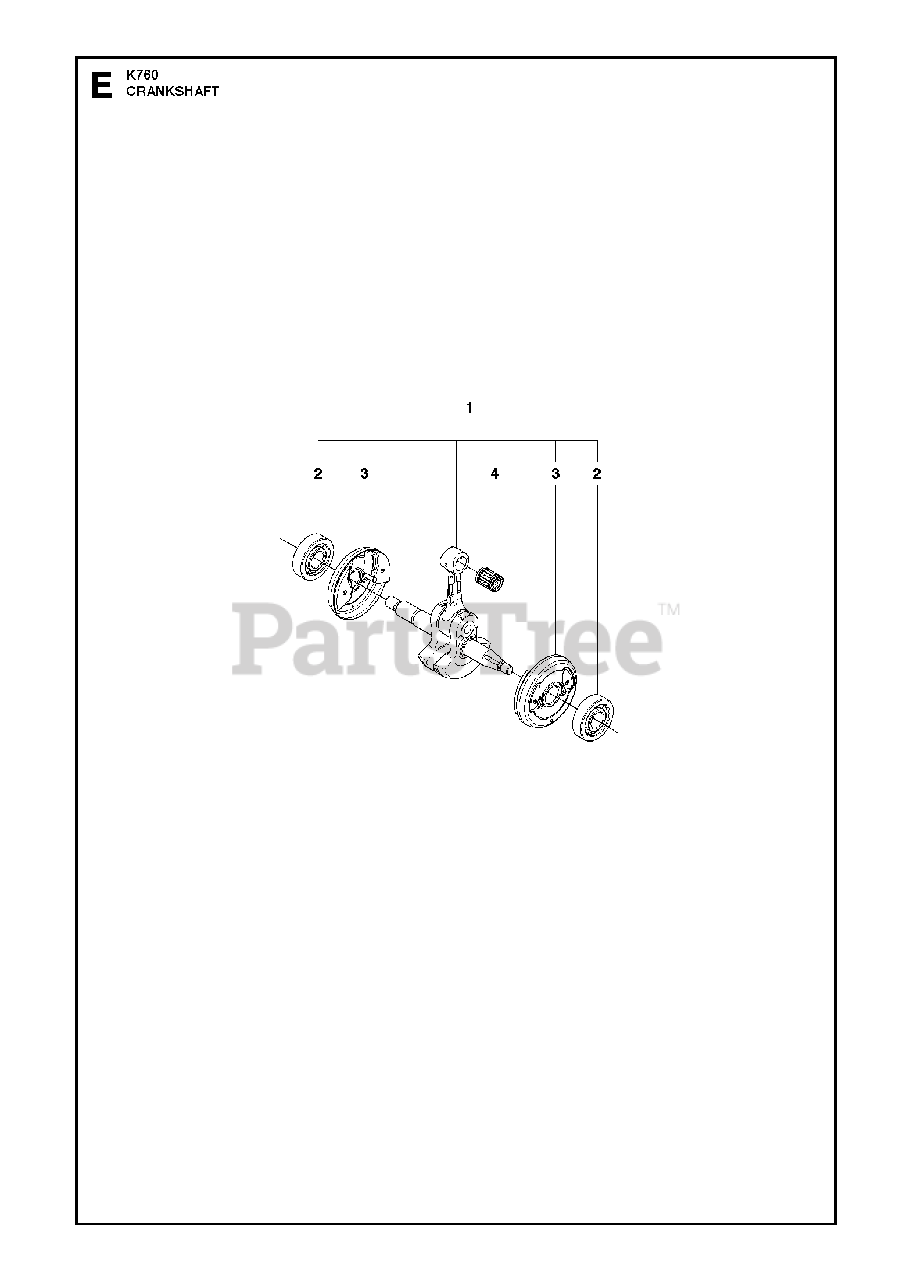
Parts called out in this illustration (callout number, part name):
1	CRANKSHAFT ASSYIncl. 2 - 4
2	BALL BEARING
4	NEEDLE BEARING
